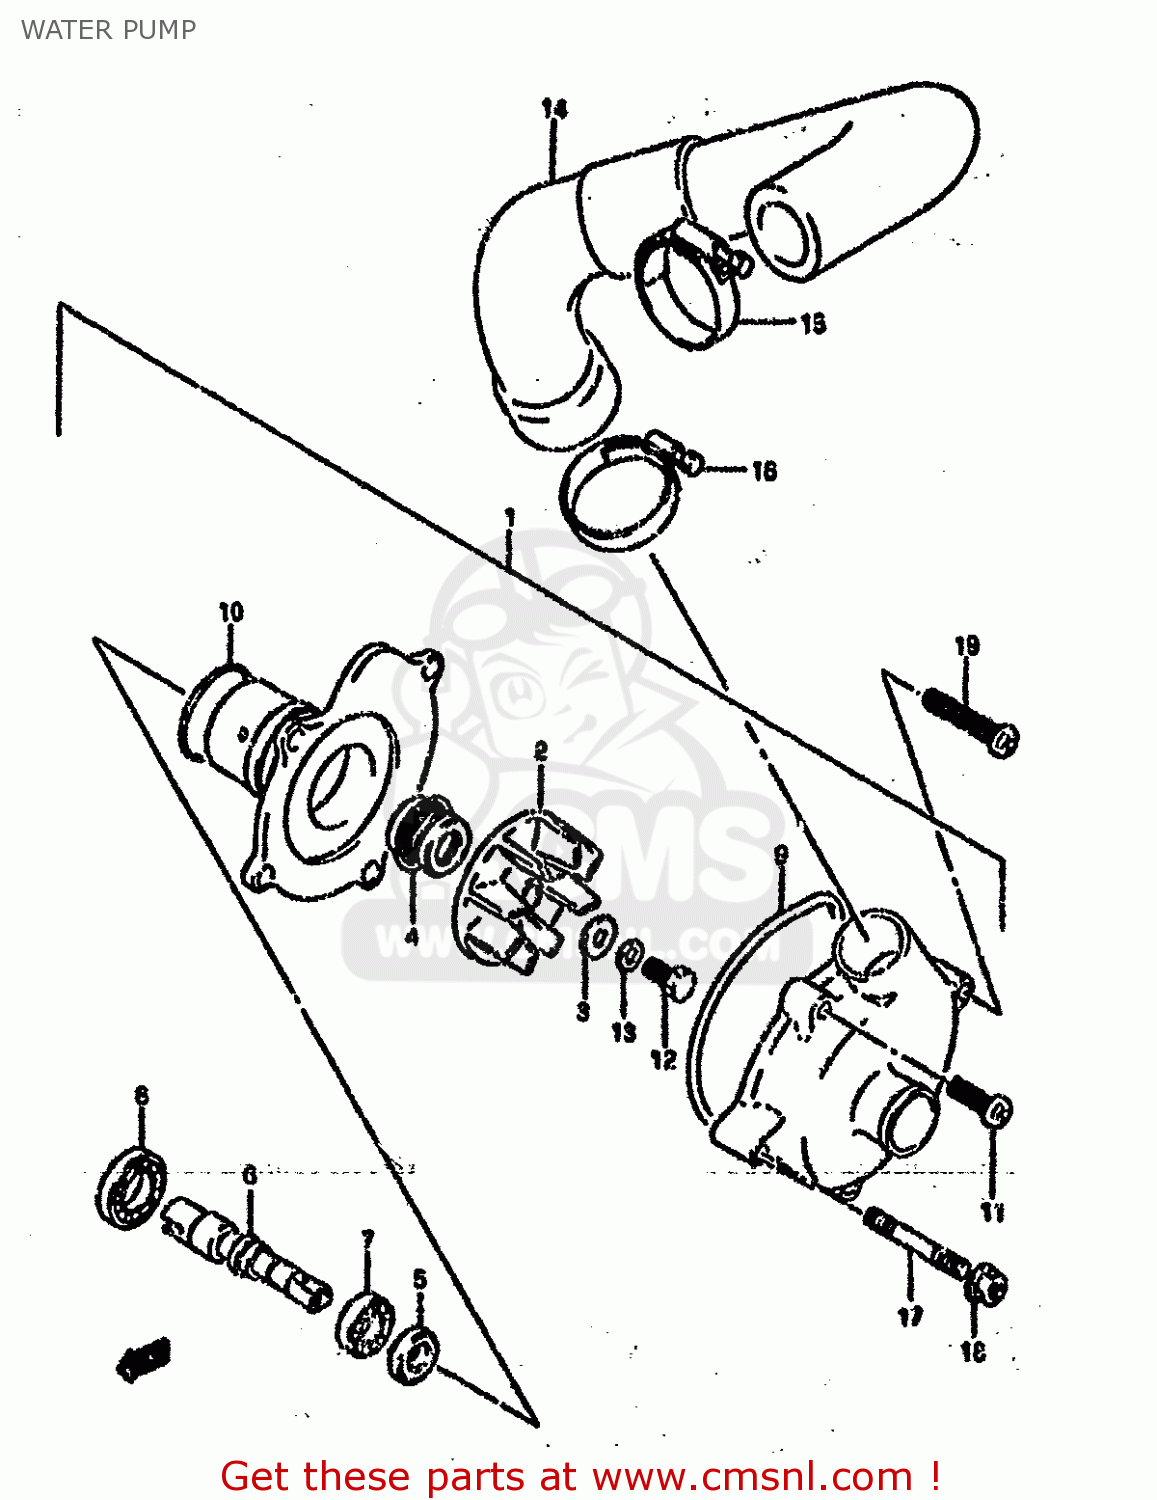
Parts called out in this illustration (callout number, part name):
1	PUMP ASSY,WATER
2	IMPELLER
3	GASKET(6X15X2.2) (NAS)
4	SEAL,MECHANICAL
5	OILSEAL
6	SHAFT
7	BEARING(10X26X8)
8	BEARING(12X28X8)
9	O RING
10	O RING,WATER PUMP HOLDER
11	SCREW 6X16
12	BOLT(6X13)
13	WASHER
14	HOSE,WATER PUMP OUTLET
15	CLAMP
16	CLAMP
17	BOLT,STUD
18	NUT
19	SCREW
